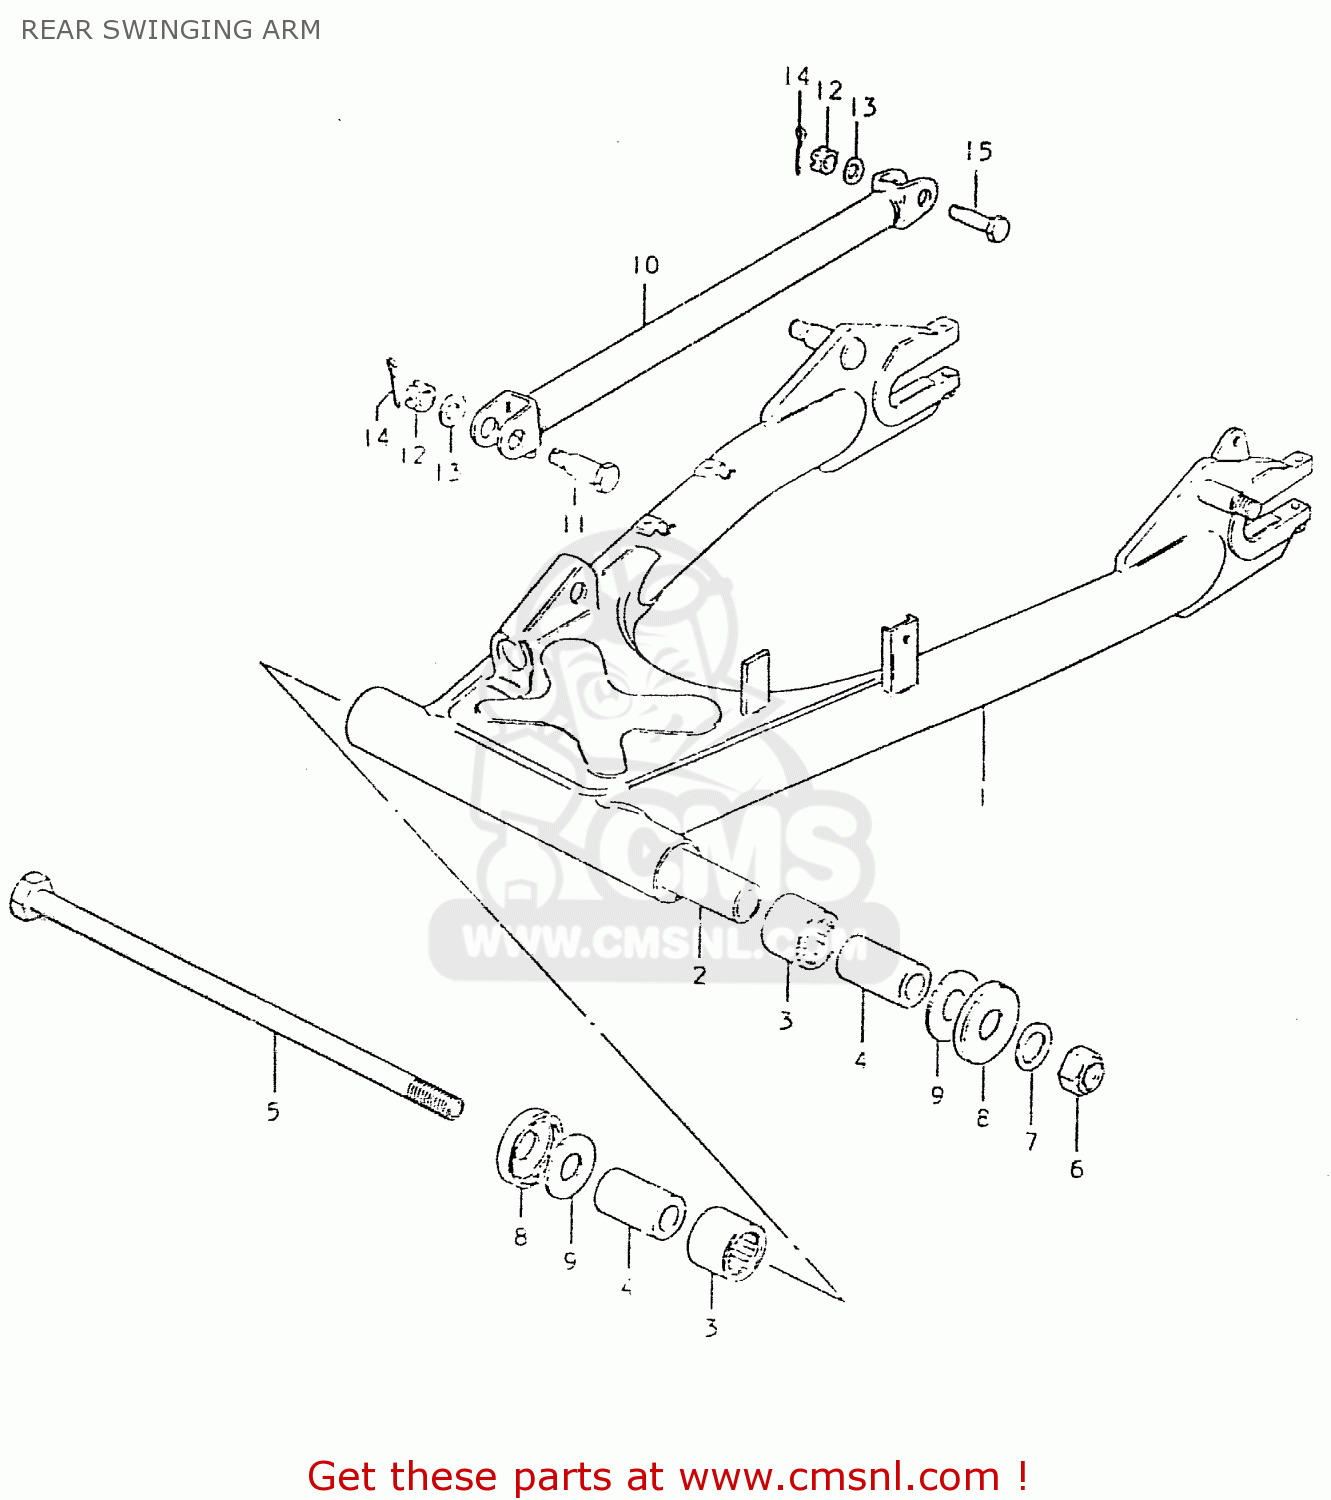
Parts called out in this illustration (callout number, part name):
1	SWING ARM ASSEMBLY,REAR
2	SPACER,RR SWGARM PIVOT CTR
3	BEARING(22X29X30)
4	SPACER,RR SWGARM PIVOT
5	SHAFT,REAR SWING ARM
6	NUT 14MM
7	WASHER
8	COVER,REAR SWING ARM DUST
9	WASHER(14.2X34X1)
10	LINK,REAR TORQUE
11	BOLT
12	NUT
13	WASHER
14	PIN 20X20
15	BOLT(10X39)
